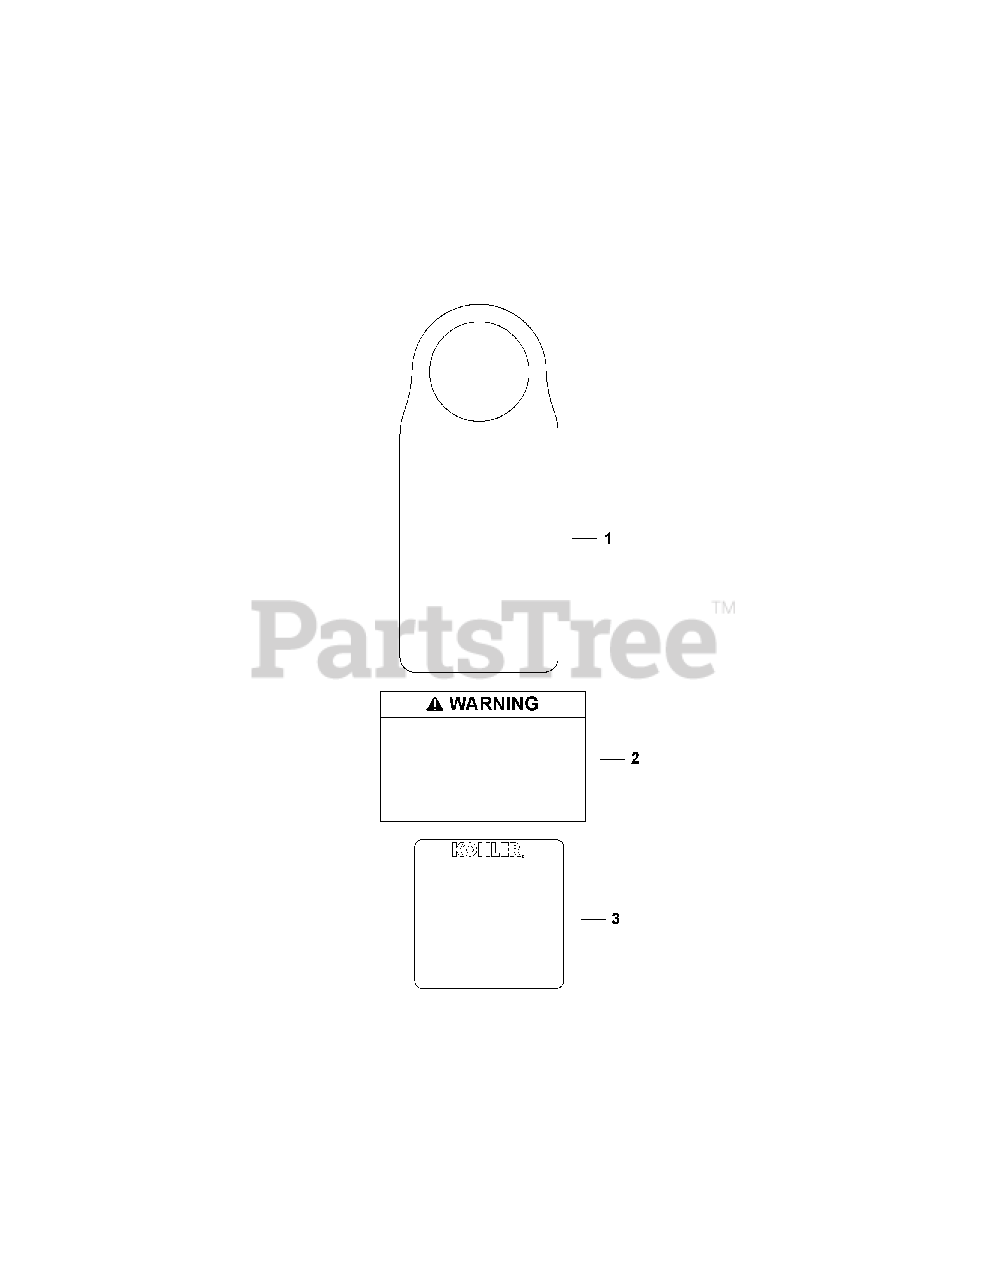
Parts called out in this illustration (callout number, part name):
1	Tag, Maintenance Hang
2	Decal, Warning
3	Nameplate, Service
